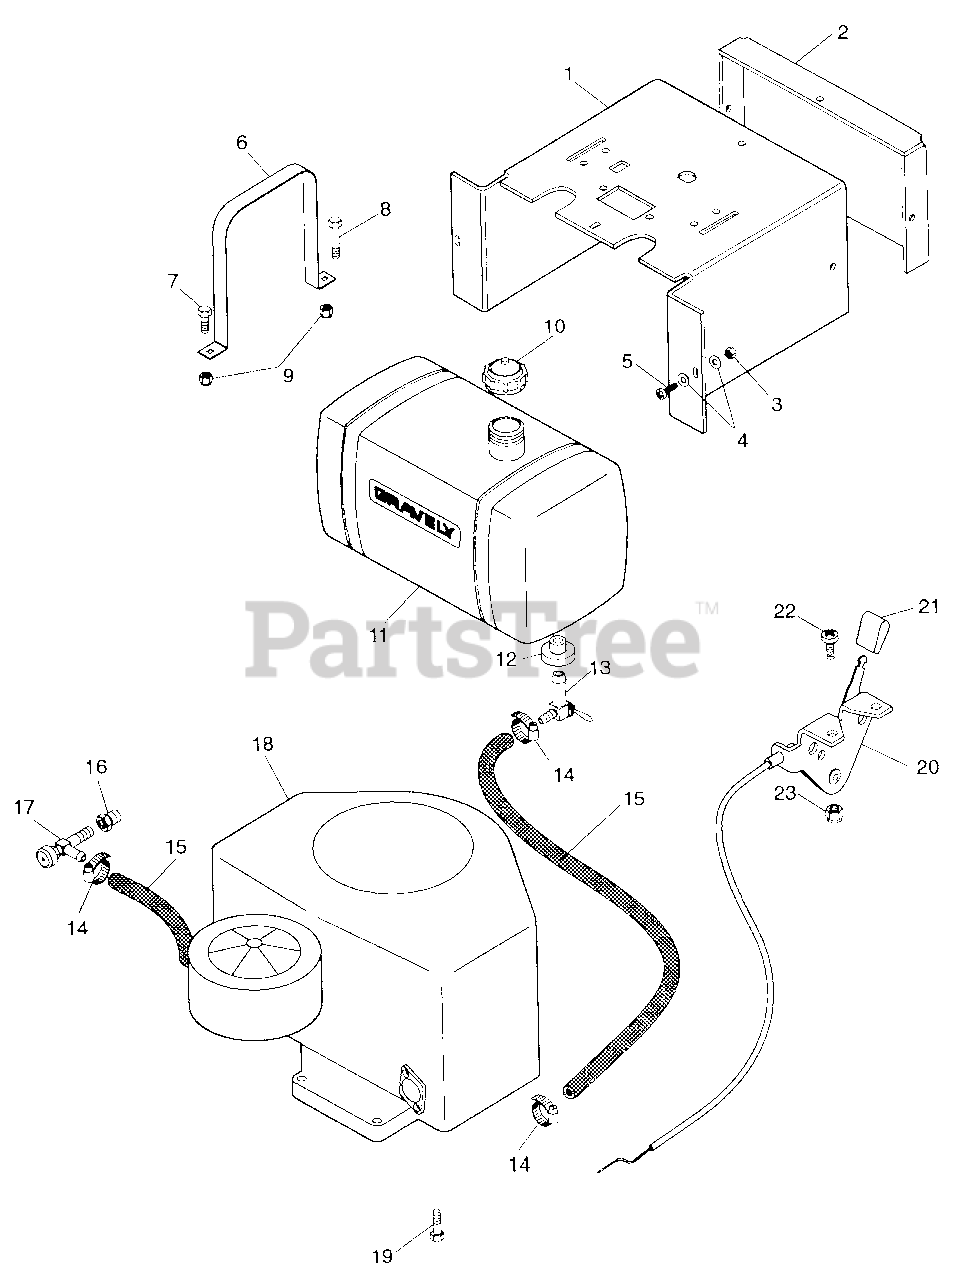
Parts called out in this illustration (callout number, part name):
1	PNL, SILKSCREEN
2	CVR, INSTRUMENT PANEL
3	NUT-LK-NYL .250-20 PL
4	WSHR-FL-STL .281 X .62 X .065 PL
5	SCR-MCH ,25-20 PAN HD
6	STRP, FUEL TANK
7	BLT-HEX .25-20 X .63
8	BLT-HEX .25-20 X 1.00 PL GR 5
9	NUT-LK-NYL .250-20 PL
10	CAP, FUEL TANK
11	TANK, FUEL PM 200
12	BUSHING
13	VALVE, BALL SHUT-OFF
14	HOSE CLAMP
15	GAS LINE-BULT
16	ADAPTER, OIL DRAIN
17	COCK, OIL DRAIN
18	ENGINE, 20 HP KOHLER CV20S
19	SCR-TAP .375-16 X 1.0 HWH PL TR
20	ASM, THROTTLE CONTROL
21	KNOB
22	SCR-MCH 10-32 X .50 PHD
23	NUT-LK 10-32 NY PL
